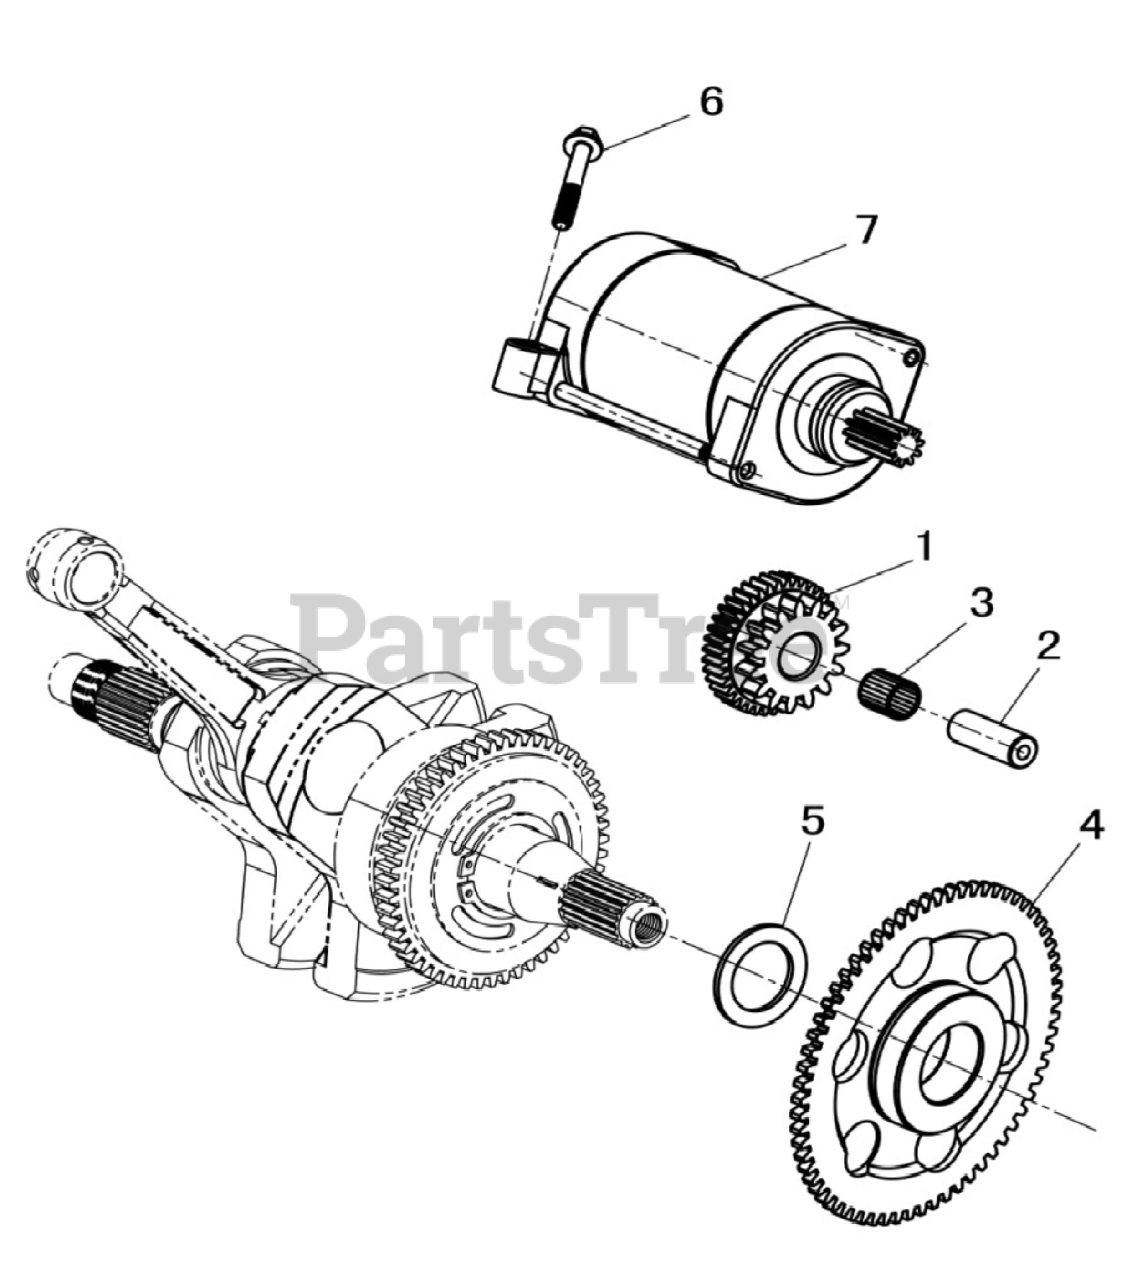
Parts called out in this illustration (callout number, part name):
1	PINION GEAR
2	Duplicate Gear Shaft
3	Needle Bearing KBK121618
4	DISK GEAR ASSEMBLY
5	Washer 25x39x1
6	Hex flange bolts M6x30
7	STARTER ASSEMBLY
